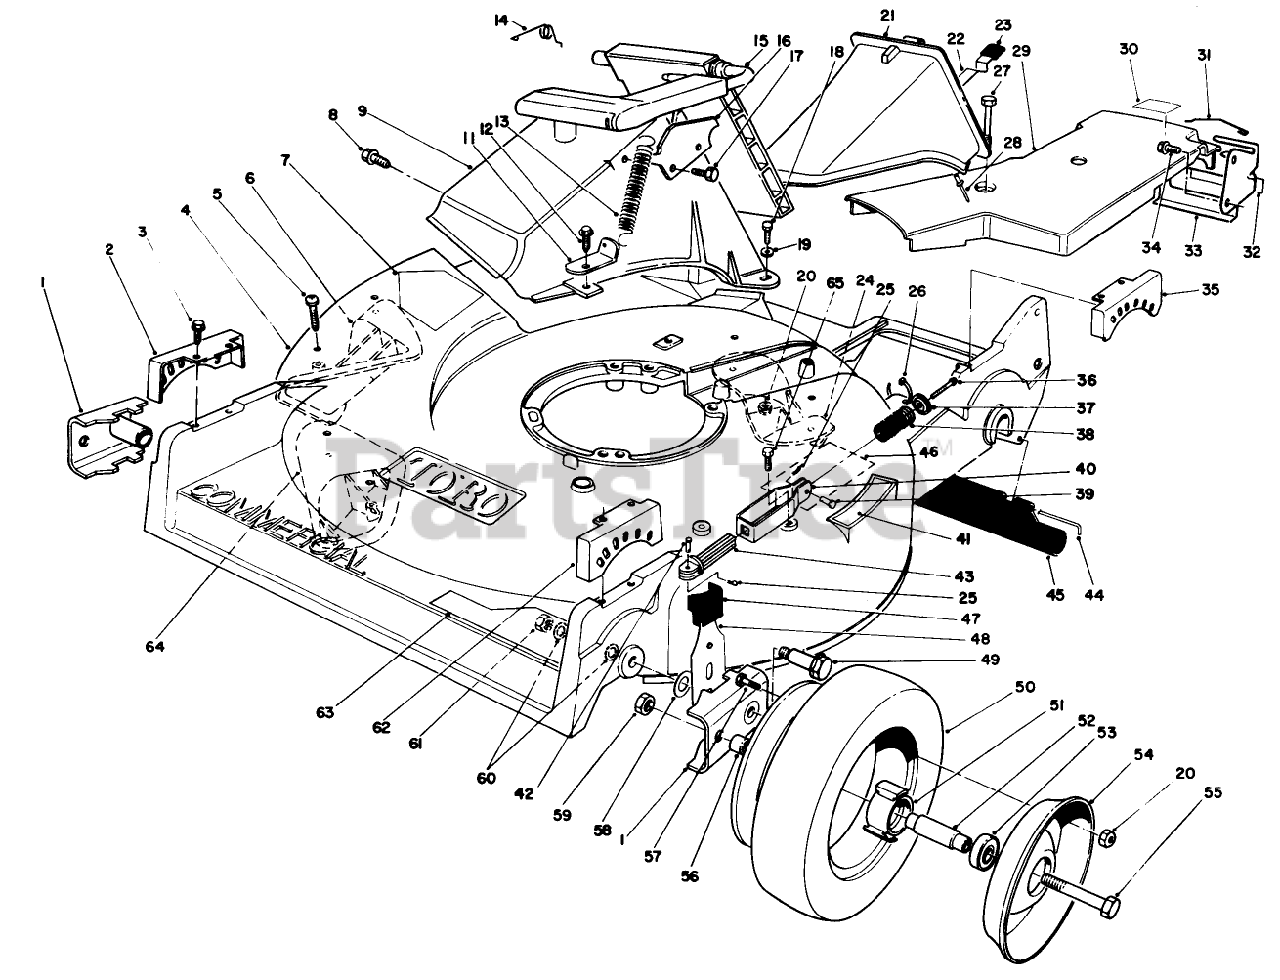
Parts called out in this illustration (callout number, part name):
1	PIVOT SCREW
2	SPACER-WHEEL
3	PIVOT ARM
4	SPRING ARM ASM-FRONT
5	KNOB-ARM
6	SPACER-PIVOT
7	FRT RIGHT QUAD
9	BAG CHUTE PIN
10	BAG CHUTE CLIP PIN
13	LIFT LOOP
14	DECAL-DANGER
15	DEFLECTOR SPRING
19	NUT-LOCK, NI
20	Spacer-Handle Latch
24	SCREW-HH
25	REAR PIVOT SCREW
26	SHIELD ROD
27	WASHER-BELLEVILLE
28	HANDLE LATCH SPACER
29	STEP PAD DECAL
30	SCREW-HH
32	CRNKSHFT PROTECT ASM
33	WASHER-LOCK, INTERNAL
34	SCREW-THD ROLL, HWH
37	SCREW-HH
38	WASHER-LOCK
39	KEY-SQUARE
40	SCREW-CARR
42	NUT-LOCK, NI
43	NUT-LOCK, NI
46	BEARING-WHEEL
47	SPACER-BEARING
48	HUB-BEARING
50	SCREW-HHF
51	SCREW-HWH
